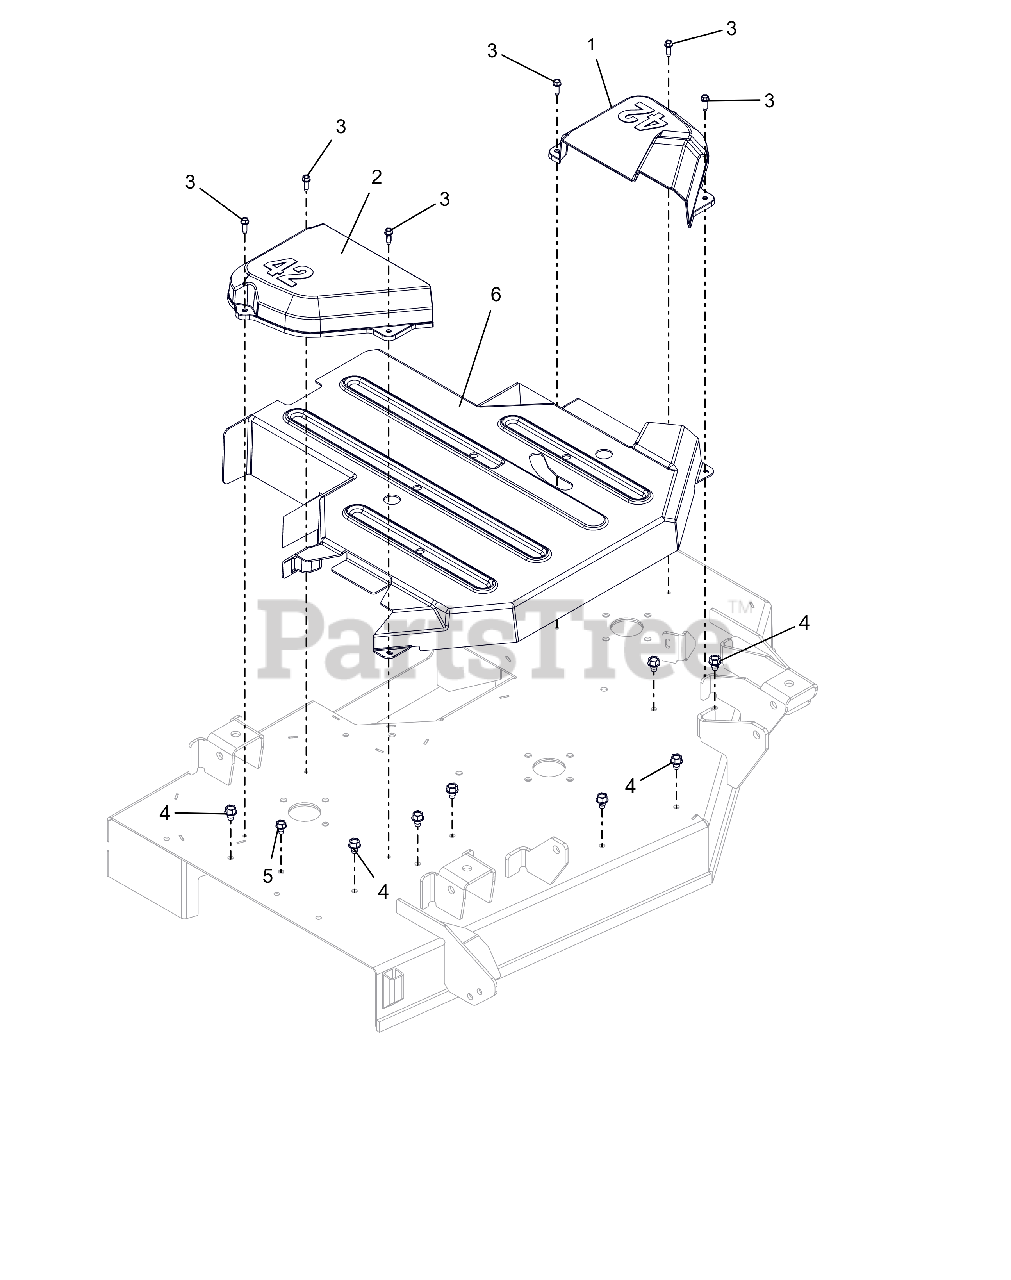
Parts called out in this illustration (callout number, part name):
1	COVER, BELT 42" LH
2	COVER, BELT 42" RH
3	SCR,TAP .25-20X.75 HWH TR ZCC
4	SCR,TAP .375-16X.50 HWH TR ZCC
5	SCR,TAP .312-18X.50 HWH TR ZCC
6	GUARD, IKON BELT-42" CE
